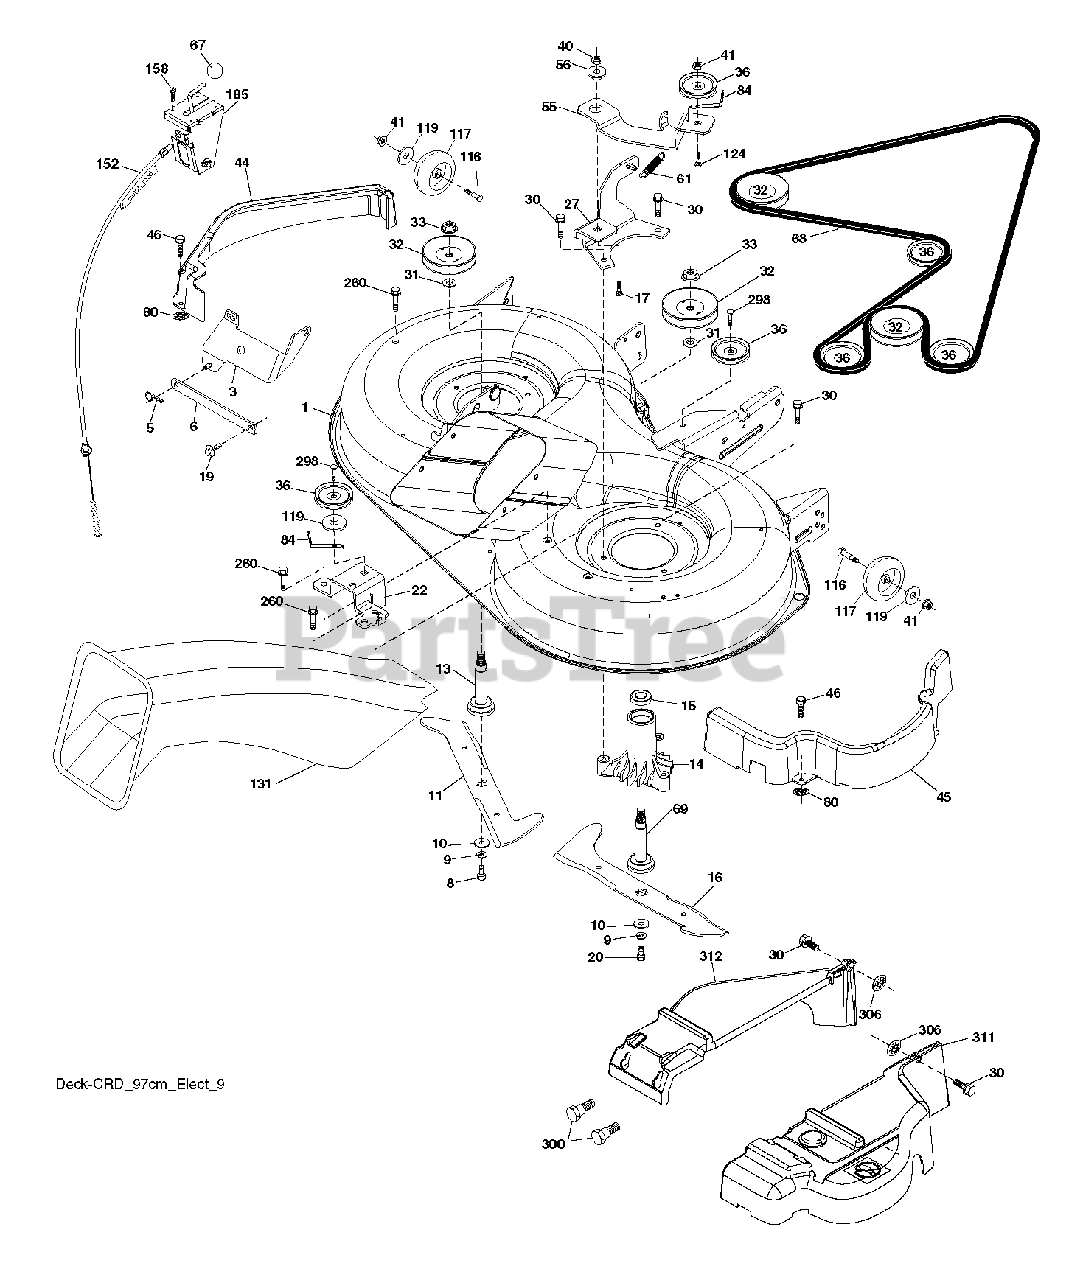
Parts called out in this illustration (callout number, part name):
1	DECK.WLDT.97.CRD.2GWB.
3	BRACKET.ASM.BAR.SWAY.CHASS
5	Retainer Spring
6	BAR.SWAY.92.CRD
8	BOLT.3/8-24X1.25 GR8
9	LOCKWASHER
10	WASHER.BLADE
11	BLADE.3N1.LH.CRD.97
13	SHAFT ASM VENT
14	HOUSING.MANDREL.VENTED (MACHD)
16	BLADE.3N1.RH.CRD.97
17	BOLT.3/8-14X1.25
19	BOLT SHD 5/16-18
20	BOLT.3/8-24X1.25GR8. LHTHRD
22	BRACKET.SUPT.IDLER.REAR.RH
27	BRACKET.ASM.SUSP.REAR.RH.
30	SCREW, WASHER HEAD
31	WASHER.SPACER.MANDREL
32	PULLEY MANDREL
33	NUT.FLANGE.LOCK.TOP
36	PULLEY.IDLER.4.25
41	NUT LOCK FLG 3/8-16 UNC
44	COVER MANDREL LEFT
45	COVER MANDREL RIGHT
46	SCREW.1/4-20X5/8
55	ARM.IDLER.92 CRD.2006
56	SPACER.RETAINER.MOWER
61	SPRING
67	KNOB T (3/8 HOLE)
68	BELT.DRIVE.CRD.97.2010
69	SHAFT.ASM.W/LWR.BRG.RH.THREAD
80	PALNUT 1/4
84	KEEPER, BELT IDLER
116	BOLT.SHOULDER.3/8-16X3-5/8.
117	WHEEL. GUAGE RALLY
119	WASHER
124	BOLT.3/8-16X1.50
131	CHUTE BAGGER
158	SCREW
185	HEAD ASM. CABLE CLUTCH
260	SCREW 3/8-16X1/2
298	SCREW LT
300	BOLT.SHOULDER
306	BOLT.SHOULDER
311	COVER RIGHT
312	COVER LEFT
